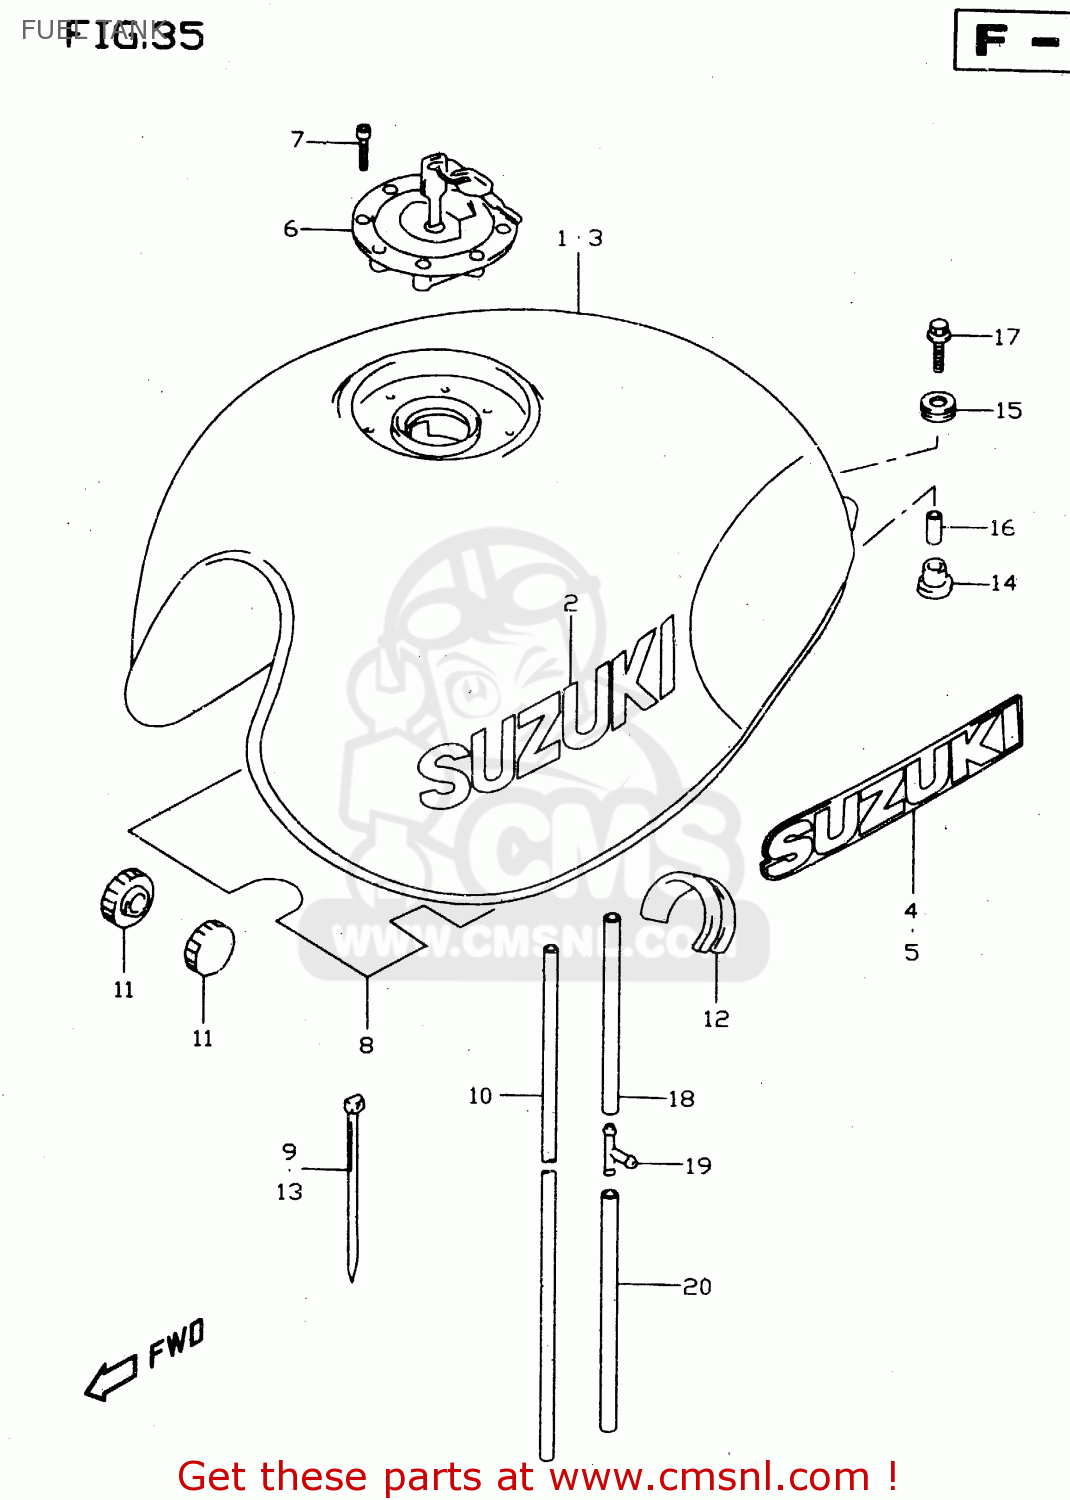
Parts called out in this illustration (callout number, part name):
1	TANK ASSY,FUEL
2	EMBLEM,FUEL TANK
3	TANK ASSY,FUEL(BLACK)
4	EMBLEM,SUZUKI,R
5	EMBLEM,SUZUKI,L
6	CAP SET,FUEL TANK
7	BOLT(5X20)
8	COVER,FUEL TANK UNDER
9	CLAMP(L:165)
10	HOSE,FUEL TANK BREATHER
11	CUSHION
12	CUSHION,FUEL TANK SIDE
13	CLAMP(L:250)
14	CUSHION
15	CUSHION,FUEL TANK RR
16	SPACER(6.5X9X18)
17	BOLT
18	HOSE,FUEL TANK DRAIN NO.1
19	3 WAY
20	HOSE(7X10.2X2000)
